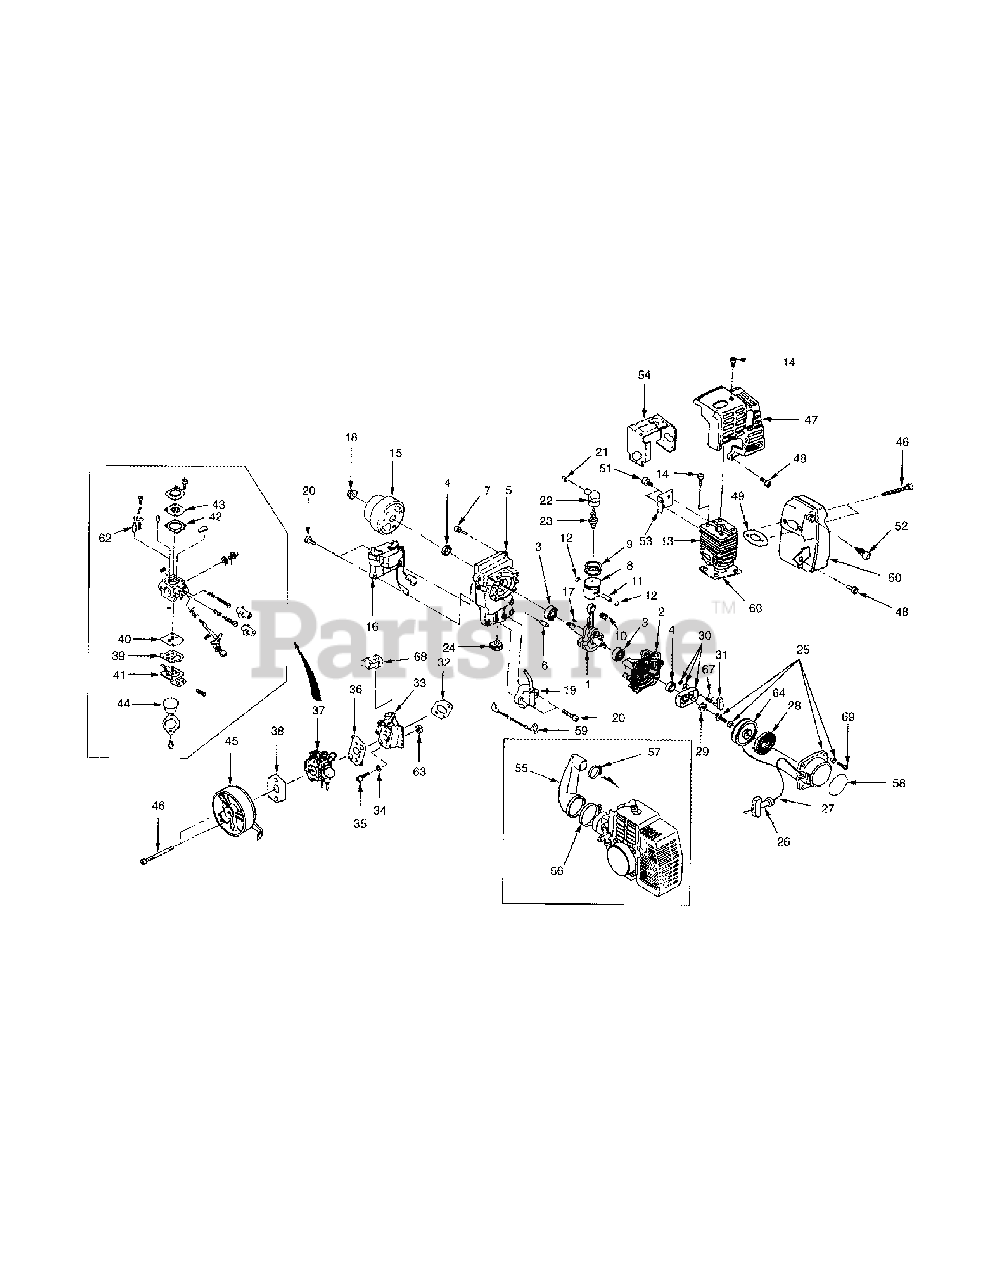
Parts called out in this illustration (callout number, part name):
2	Crankcase Assembly
3	Bearing, Ball, 6202
5	Crankcase Assembly
8	Piston Assembly
9	Ring, Piston
10	Bearing, Needle
12	Clip, Piston Pin
13	Cylinder
15	Flywheel, Magneto
19	Coil Assembly, Ignition
23	Spark Plug
25	Recoil Assembly
26	Knob, Starter
27	Rope, Starter
28	Spring, Spiral
30	Pulley Assembly, Starter
32	Gasket, Insulator
34	Washer
36	Gasket
37	Carburetor Assembly
38	Gasket
40	Diaphragm, Pump
41	Body, Pump
43	Diaphragm, Metering
44	Rubber
47	Cowling, Cylinder
49	Gasket, Muffler
53	Plate, Baffle
54	Cowling
55	Elbow, Intake
59	Harness, Wire
60	Gasket, Cylinder
62	Valve, Float
